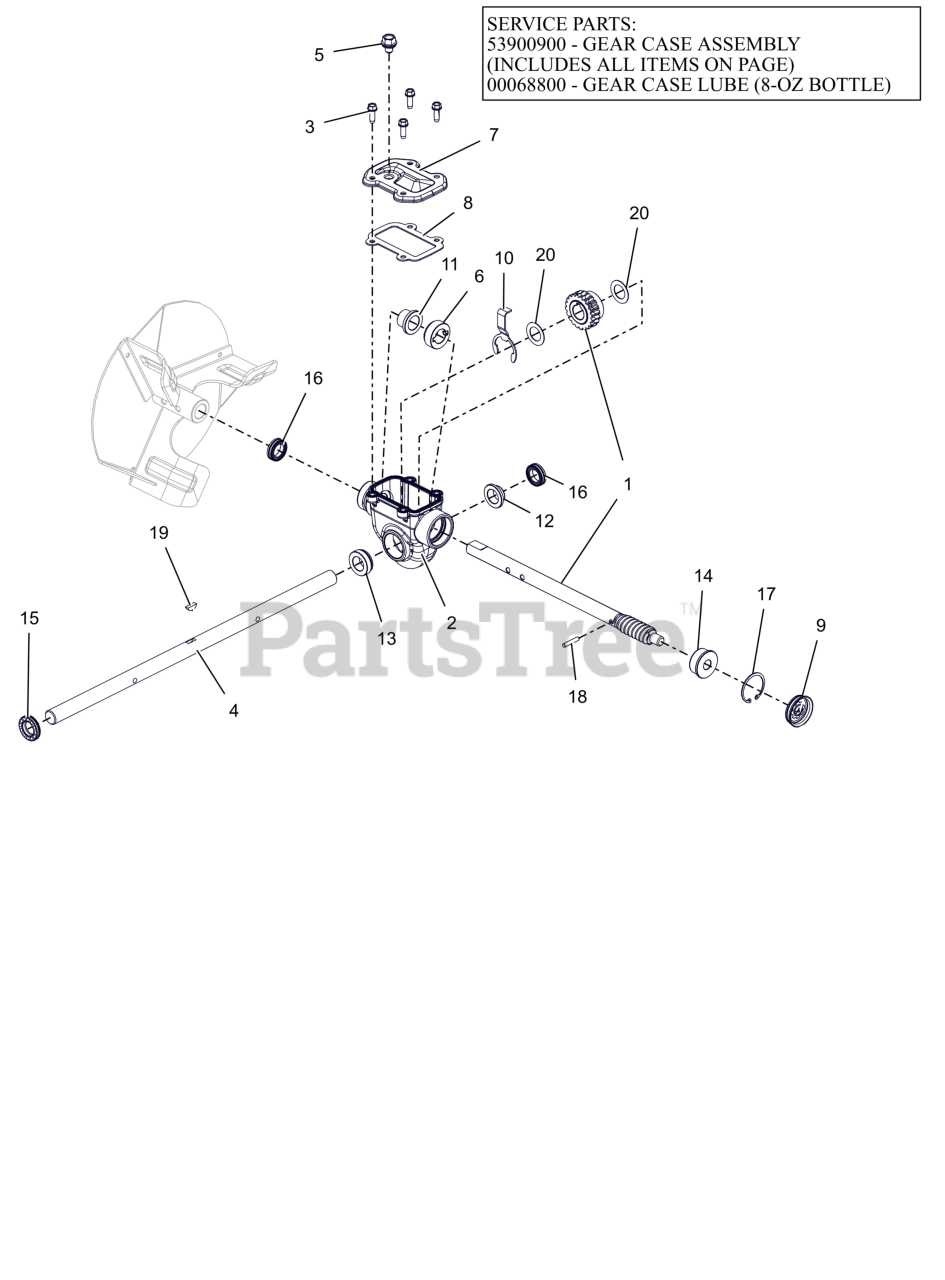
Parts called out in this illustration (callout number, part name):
1	SHAFT AND WORM GEAR ASSEMBLY
2	GEARCASE, COMPACT ALUMINUM
2	GEAR CASE, 20" ALUM SM TOP-LD
2	ARIENS L3 LUBE, 8 OZ BOTTLE
3	SCR,TAP .25-20X.75 HWH TR ZCC
4	SHAFT, RAKE - 20" (.750 DIA)
5	SCR, .380-15X.500 W/SEAL WASHER
6	THRUST COLLAR, .75" ID SLIPFIT
7	COVER, TOP - COMPACT
8	GASKET, TOP - COMPACT GEARCASE
9	COVER, GEAR CASE 1.50"
10	BUSHING RETAINER, COMPACT
11	BSHG-FLG .755X.878X.75X1.25
12	BSHG-FLG .755X.878X.424X1.25
13	BSHG-FLG COMPACT, RIGHT
14	BSHG-FLG .503X1.303X.62X1.465
15	SEAL-OIL .748X1.300X.250 TBC29
16	SEAL-OIL .748X1.125X.312 TBC29
17	RG-RTNG-INT 1.500X.050
18	PIN-STR .188X1.00 6150
19	KEY-WDRF .19X.63 HRD #61
20	WSHR, FLT .760X1.225X.032 ZCC
